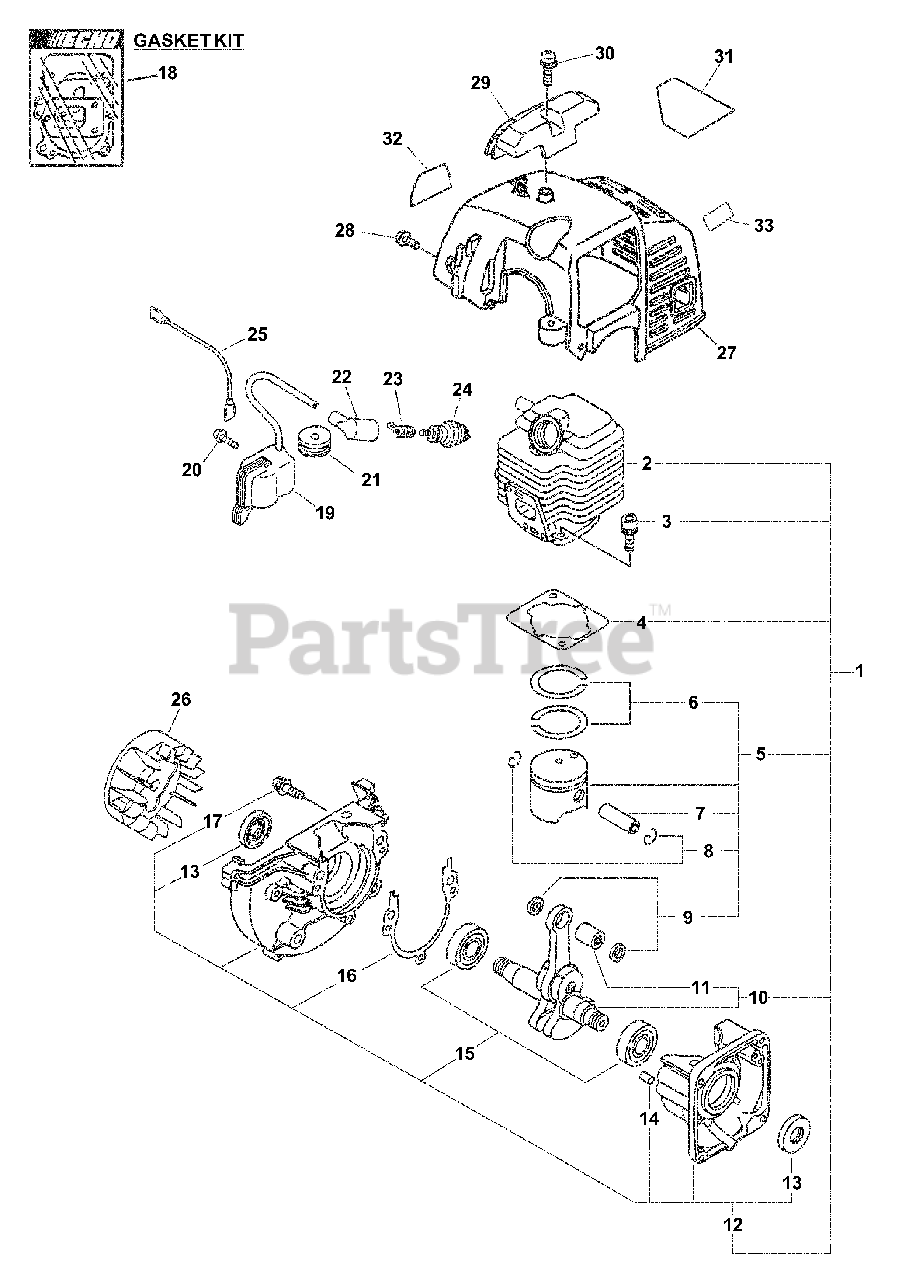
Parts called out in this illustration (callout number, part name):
1	SHORT BLOCK
2	CYLINDER
3	BOLT 5×22
4	GASKET, CYLINDER
5	PISTON KIT
6	RING, PISTON
7	PIN, PISTON 8
8	RING, SNAP
9	WASHER, THRUST
10	CRANKSHAFT ASSY
11	BEARING, NEEDLE
12	CRANKCASE KIT
13	SEAL, OIL 12
14	PIN, LOCATING 4
15	BEARING, BALL - 6201 C3
16	GASKET, CRANKCASE
17	BOLT 5×28
18	GASKET KIT
19	COIL, IGNITION
20	SCREW 4×22
22	CAP, SPARK PLUG
23	TERMINAL, SPARK PLUG
24	SPARK PLUG - BPM7A
25	LEAD
26	FLYWHEEL
27	COVER, ENGINE
28	SCREW 4×12
29	GUARD, TOP - BLACK
30	SCREW 5×16
31	LABEL, CAUTION
32	LABEL, MODEL
33	LABEL, CAUTION - HOT
